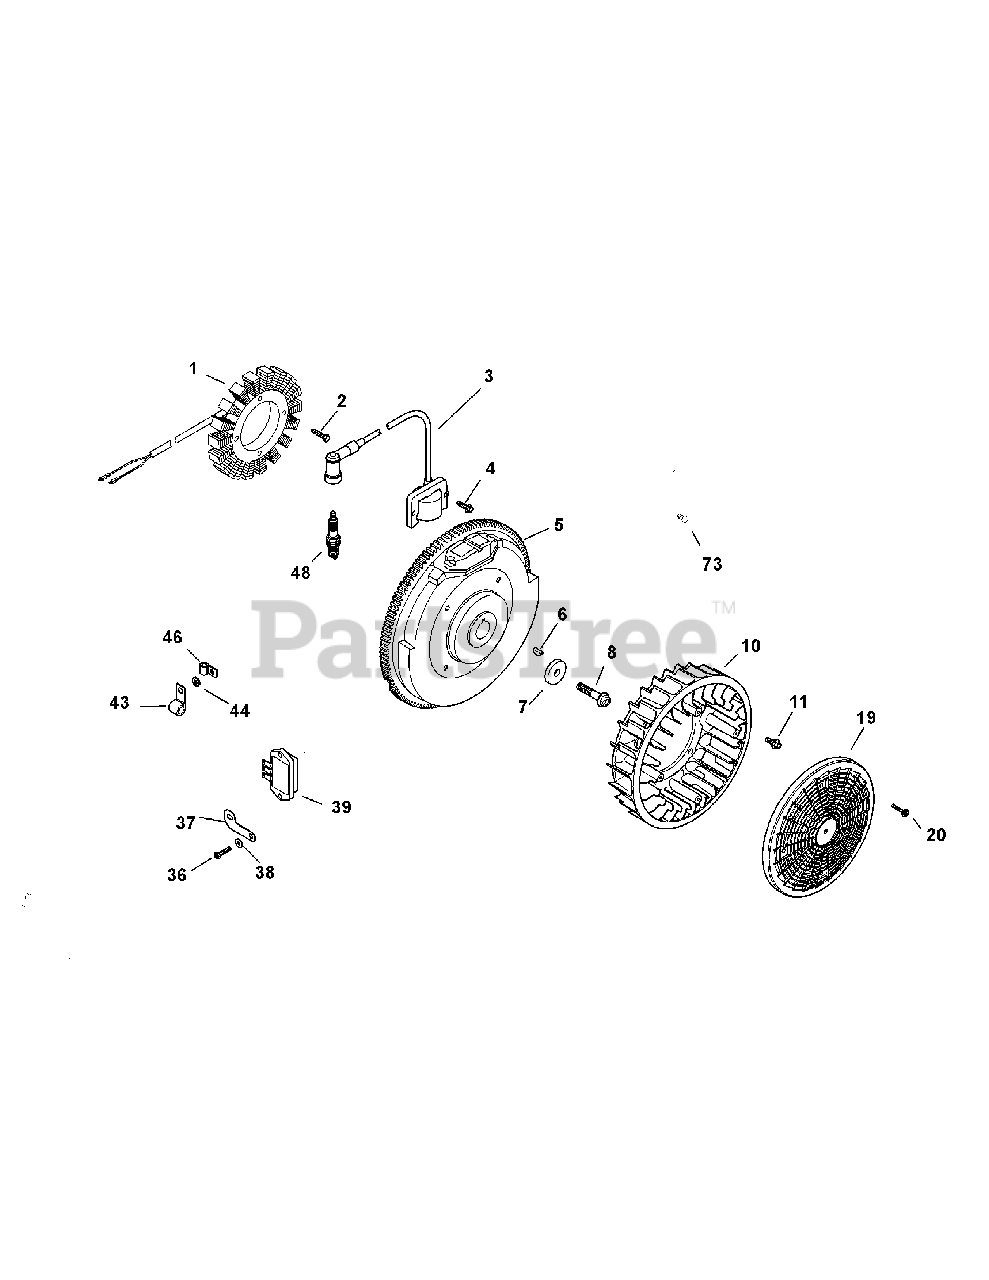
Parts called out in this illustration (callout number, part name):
1	Kit, 15 / 20 Amp Stator
2	Screw, Thd Frm M5X0.8X25
3	Kit, Module Ignition (CDI Fixed)
4	Screw, Flg Thd Frm M5X.8X20
6	Key, 3/16" X 5/8"
7	Washer, Flat 13/32"
8	Screw, Flg M10X1.5X45
10	Fan
11	Bolt, Shoulder
19	Screen,Grass Low Prfle W/O Hole
20	Screw, Sems Dog Point
36	Screw, Hex Flange Hi-Lo
37	Bracket, Ground Strap
39	Regulator/Rectifier
43	Clip, Cable
44	Washer, Flat 1/4" (O.D. 1/2")
48	Spark Plug (Pro Series)
73	Screw, Wsh Hd Tap #8-18X1/2"
